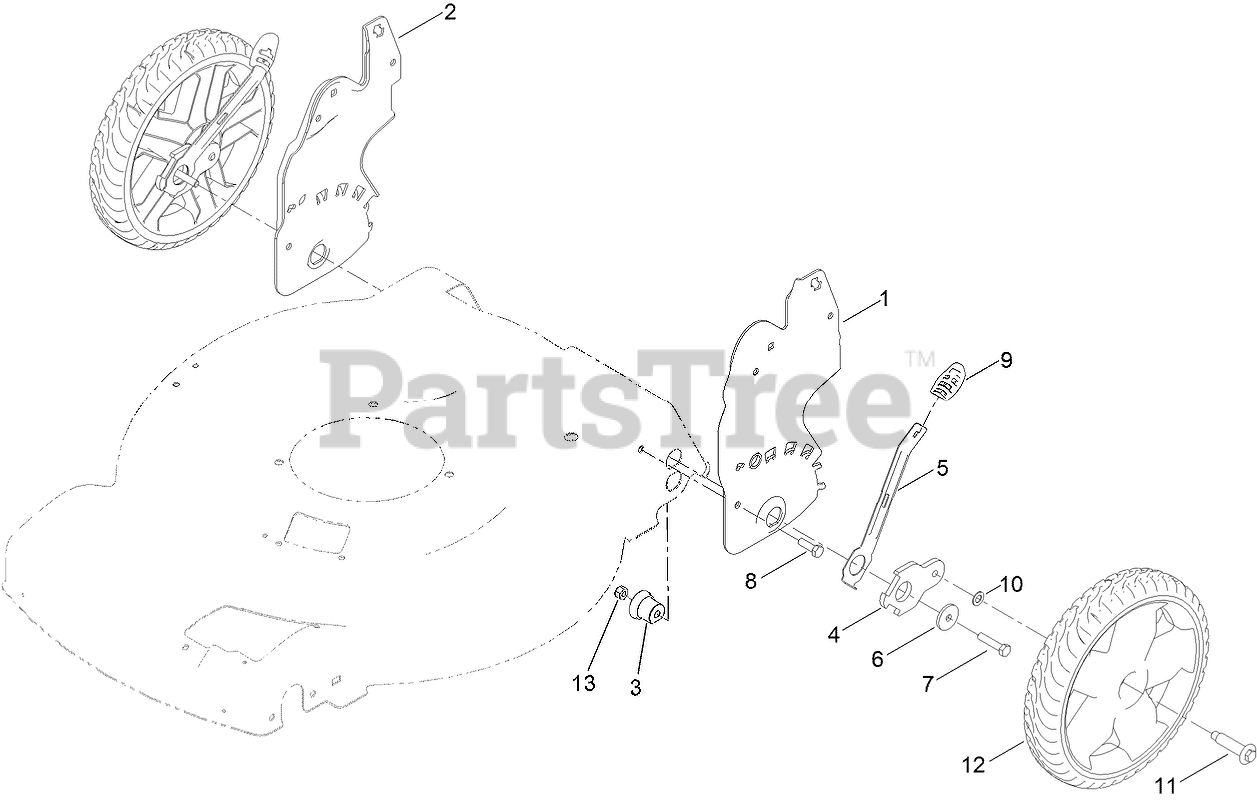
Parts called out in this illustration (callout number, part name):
1	PLATE-HOC, LH
2	PLATE-HOC, RH
3	BUSHING-MOUNT, HOC
4	ARM-PIVOT, REAR
5	ARM-SPRING, REAR
6	WASHER-FLAT
7	SCREW-HH
8	SCREW-HH
9	KNOB-LEVER, HOC
10	WASHER
11	BOLT-SHOULDER
12	11IN WHEEL ASM
13	NUT-HEX
